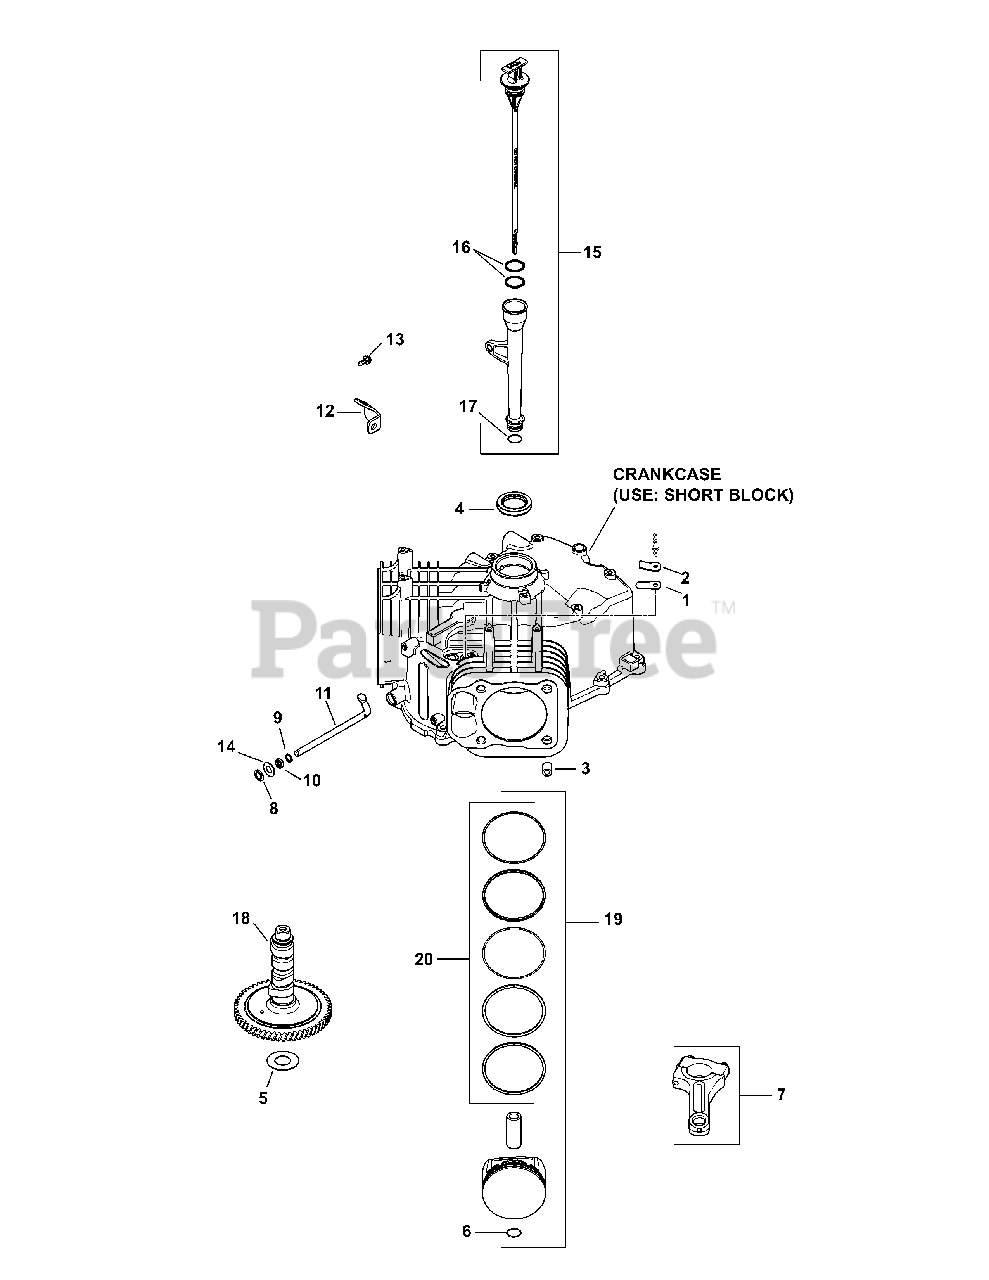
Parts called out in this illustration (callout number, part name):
1	Breather Reed
2	Breather Reed Retainer
4	Oil Seal (Helix Lip)
5	Camshaft Shim (White .028")
5	Camshaft Shim (Blue .03")
5	Camshaft Shim (Red .032")
5	Camshaft Shim (Yellow .034")
5	Camshaft Shim (Green .036")
5	Camshaft Shim (Gray .038")
5	Camshaft Shim (Black .04")
6	Piston Pin Retainer
7	Connecting Rod (Std)
8	Ring Retainer
9	Flat Washer, 11/32
10	Governor Cross Shaft Seal
11	Governor Cross Shaft
12	Oil Fill Tube Bracket
13	Flg. Thd. Frm. Screw, M5 x 0.8 x 13
14	Flat Washer, 9mm
15	Dipstick And Tube Kit
16	Dipstick O-Ring
17	O-Ring, Lower Oil Fill Tube
18	Camshaft Assembly
19	Piston w/ Ring Kit
19	Piston W/ Ring Kit (0.25) 83mm
19	Piston W/ Ring Kit (0.08) 83mm
20	Piston Ring Set, (Std)
20	Ring Set (.08)
20	Ring Set (.25)
